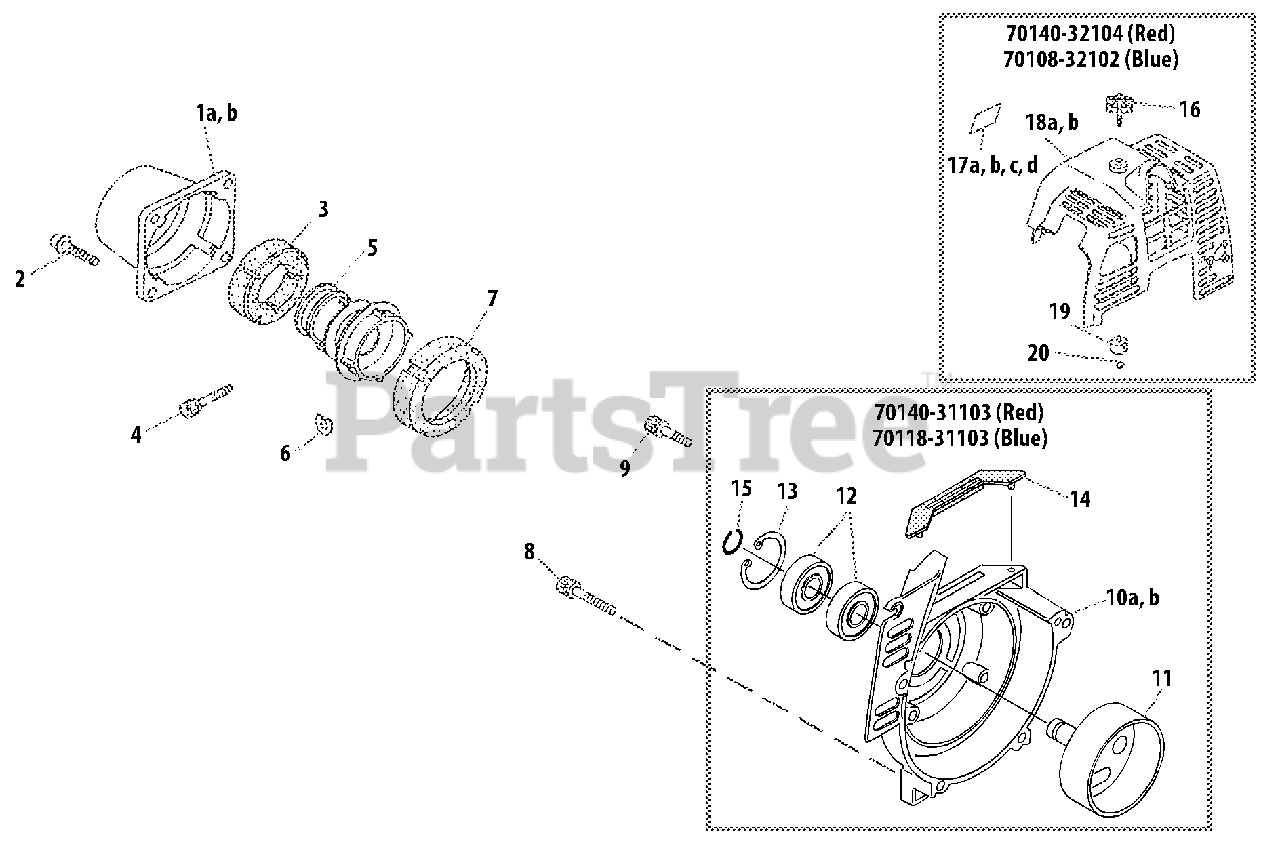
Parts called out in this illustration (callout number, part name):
1	CAP
2	SCREW - 5X16
3	CUSHION - FRONT
4	SCREW - 5X25
5	CLAMP, MAIN PIPE
6	SHIM
7	CUSHION - REAR
8	SCREW - 5X16
9	SCREW - 5X35
10	CASE, FAN
11	DRUM, CLUTCH
12	BEARING, BALL - 6000
13	RING, RETAINING - 26
14	CUSHION
15	RING, RETAINING
16	THUMBSCREW
17	LABEL - IDENTIFICATION
17	LABEL - MODEL T230XB
18	COVER, ENGINE
19	INSULATOR
20	CLIP
70108-32102	ENGINE COVER KIT - BLUE
70118-31103	FAN CASE ASSY
70140-31103	FAN CASE ASSY
70140-32104	ENGINE COVER KIT - RED
